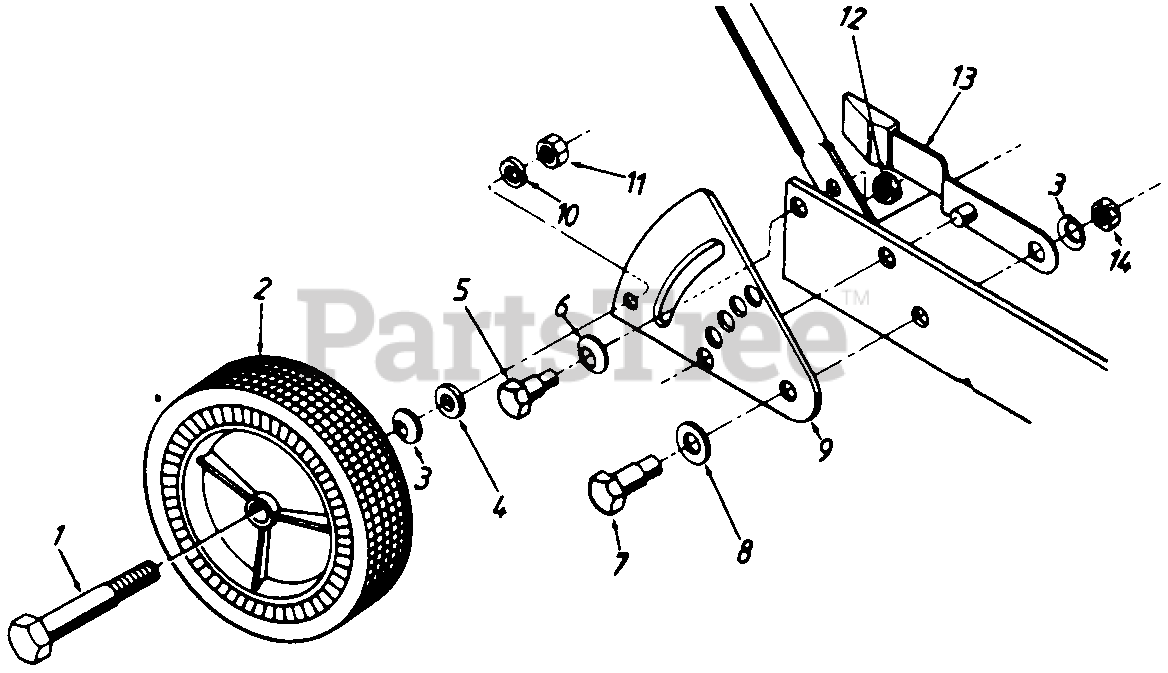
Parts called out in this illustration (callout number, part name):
1	Shld. Bolt .498" Db. x 1.45"
2	Rear Wheel
3	Bell-Wah. .40" I.D. x .88" O.D.
4	Fl-Wash. .39" I.D. x 1.12"
5	Shld. Bolt. .50" Dia. x .25" 4.
6	Bell-Wah. .515" I.D. x 1.14" O.D.
7	Shld. Bolt .50" Dia. x .2f5" 4.
8	Fl-Wash. .51" I.D. x 1" O.D.
11	Hex Nut 3/8-16 Thd.
12	Hex L-Nut 3/8-16 Thd.
13	Spriny Adj. Lever
14	Hex Jam Nut 3/8-16 Th
